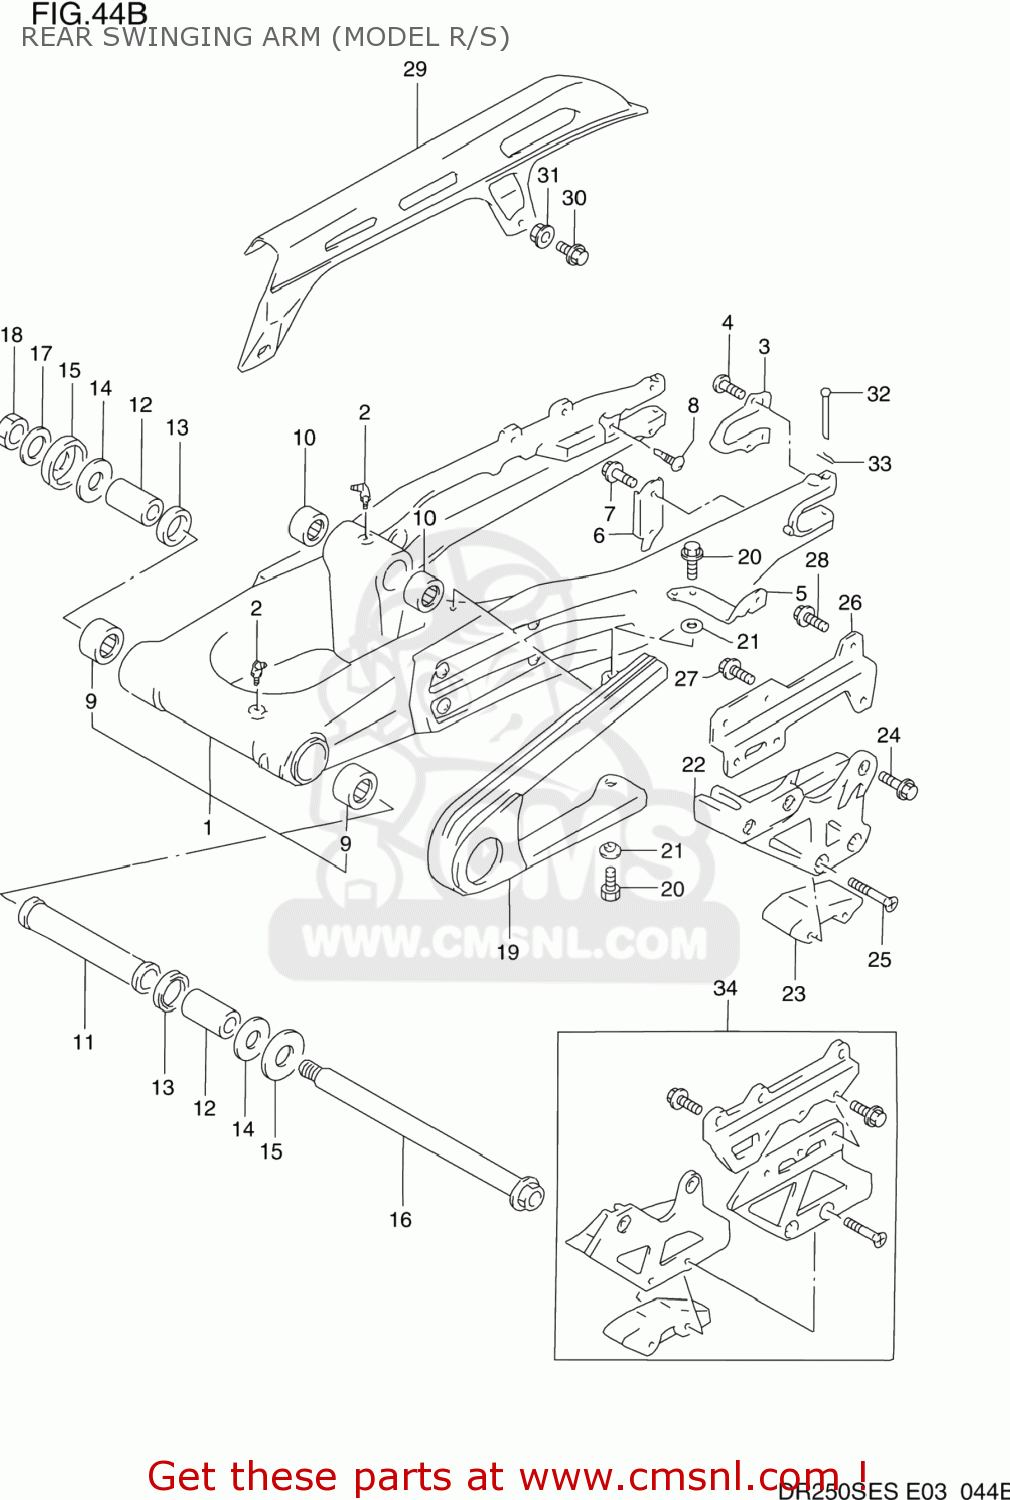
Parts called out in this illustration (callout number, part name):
1	SWINGINGARM ASSY,RR
2	NIPPLE,GREASE
3	PLATE,SWING ARM RR
4	SCREW (5X8)
5	PLATE,CHAIN CASE FTG FR
6	PLATE,CHAIN CASE FTG RR
7	BOLT
8	SCREW (M10X21)
9	BEARING(22X29X30)
10	BEARING(20X27X23.5)
11	SPACER,SWING ARM PIVOT,CENTER
12	SPACER,SWGARM PIVOT BRG
13	SEAL,OIL(22X29X4)
14	WASHER
15	COVER,SWINGINGARM PIVOT
16	SHAFT,SWINGING ARM PIVOT
17	WASHER, FIXED DRIVE FACE
18	NUT
19	BUFFER,CHAIN TOUCH DEFENSE
20	BOLT
21	WASHER
22	GUIDE,CHAIN
23	DEFENSE,CHAIN GUIDE
24	BOLT
25	SCREW
26	BRACKET,CHAIN GUIDE
27	BOLT
28	BOLT
29	CASE,CHAIN
30	BOLT
31	WASHER
32	PIN
33	CLIP
34	GUIDE SET,CHAIN
